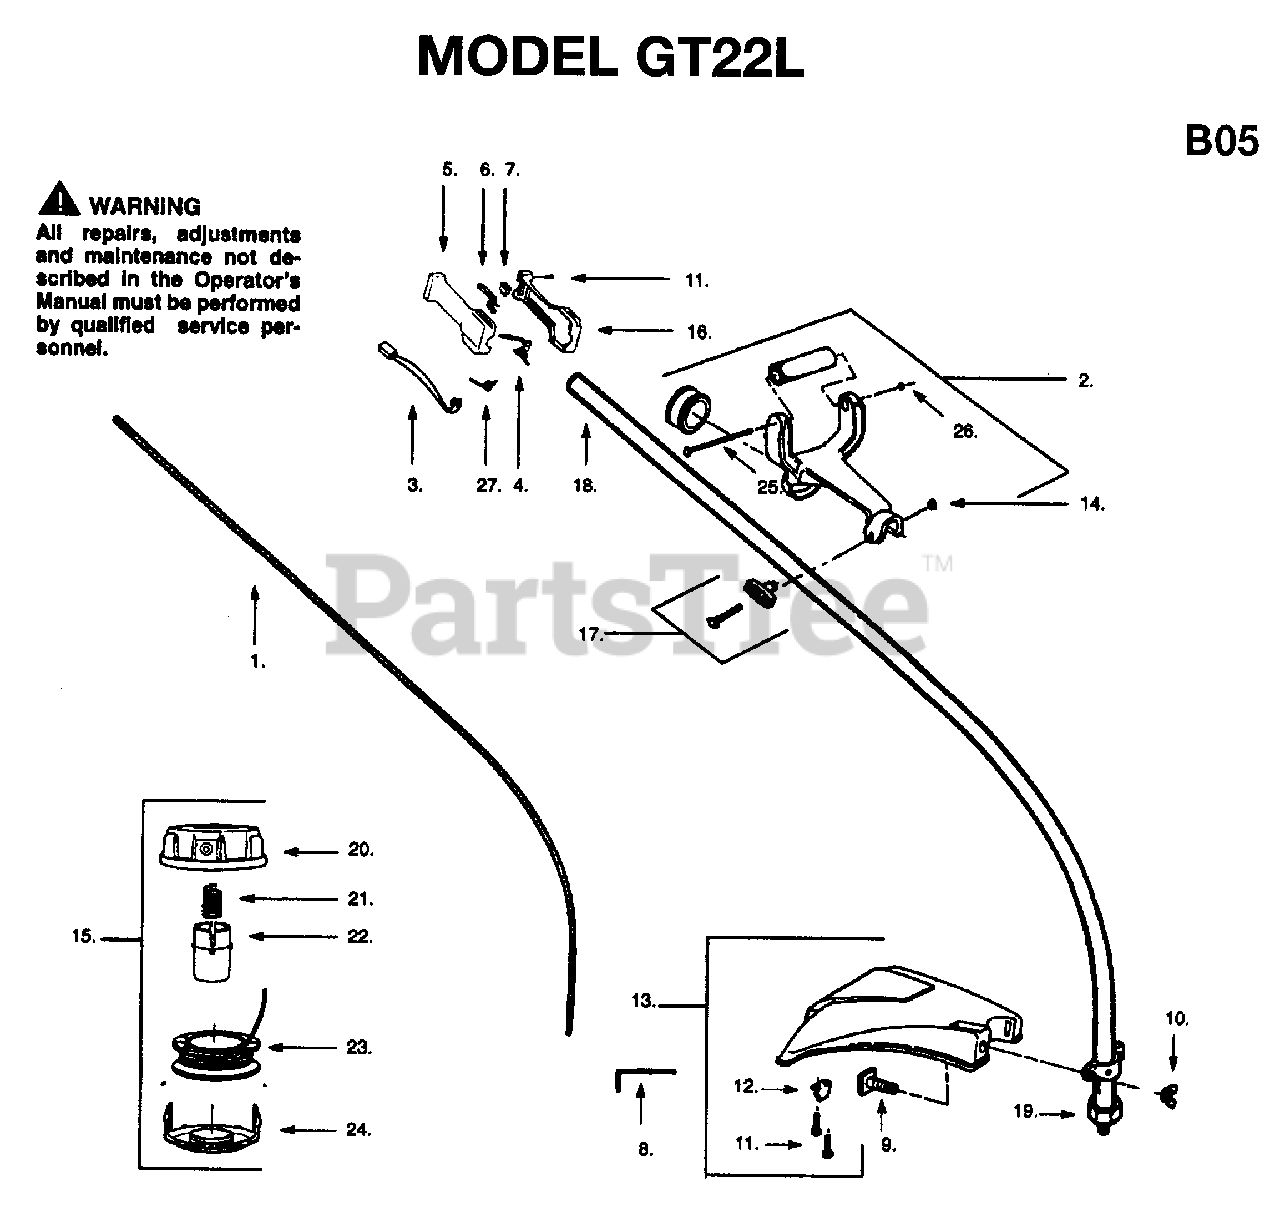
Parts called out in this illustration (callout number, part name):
1	SHAFT-FLEX (48")
2	ASS'Y-HANDLE ANTIVIB
4	THROTTLE TRIGGER
8	HEX WRENCH 5/32
9	BOLT, TYPE 2
10	WING NUT
11	SCREW-10-14 X 13/16 (PL
12	LINE LIMITER
15	CUTTING HEAD ASSEMBLY
17	KIT "T" HANDLE
18	DRIVE SHAFT
20	HUB AND SHAFT ASSY
23	SPOOL W/ LINE NLA
25	SCREW-12-24 X 4-11/16 P
26	NUT-12-24 (HEX)
27	SPRING-LEVER RETURN
